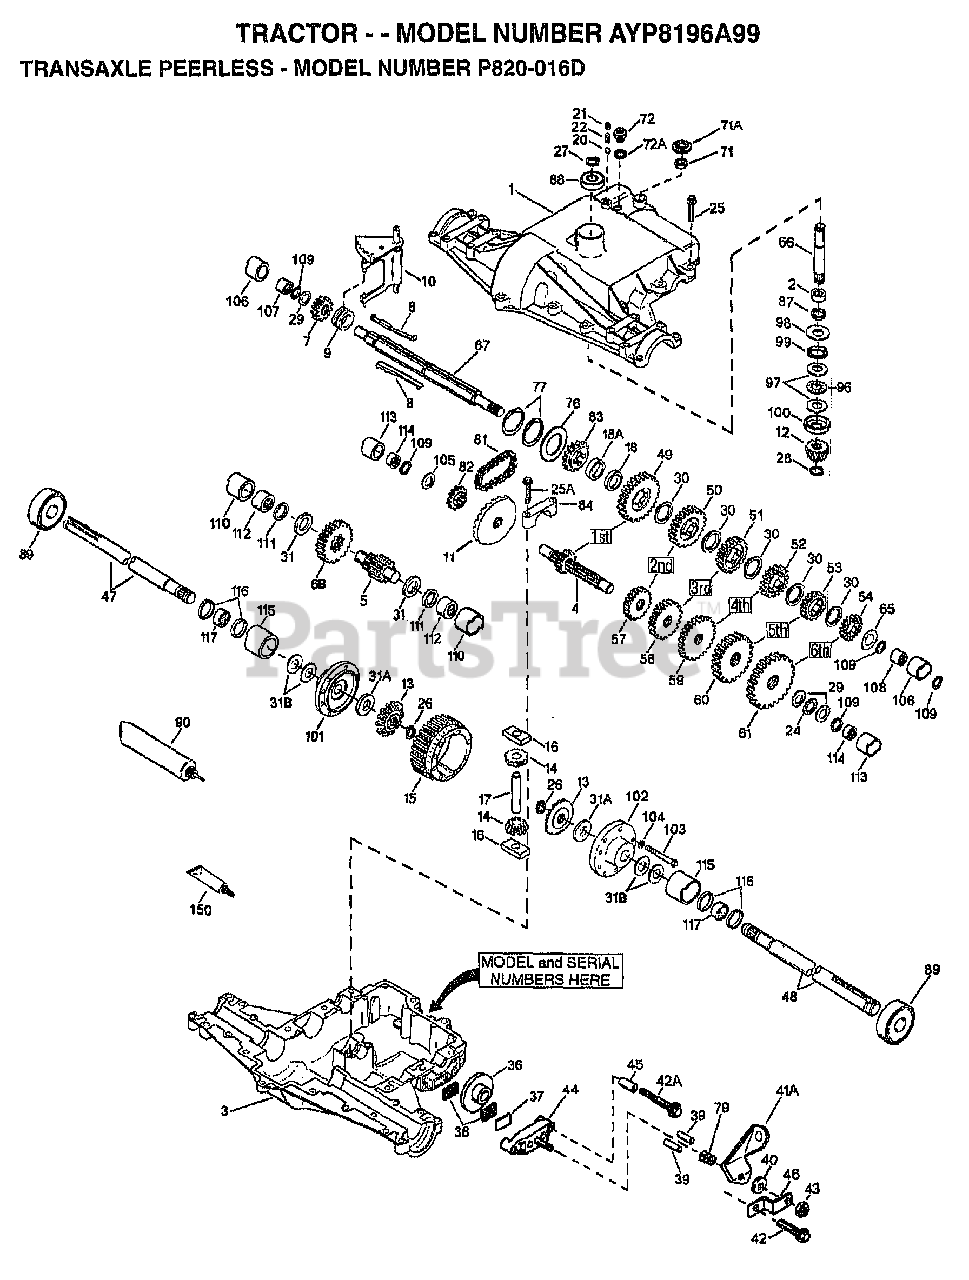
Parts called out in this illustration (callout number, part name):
1	COVER TRANSAXLE
2	BEARING NEEDLE
3	CASE TRANSAXLE
4	SHAFT COUNTER
5	SHAFT, OUTPUT, 9T
6B	GEAR, OUTPUT, 35T
7	GEAR, SPUR, 15T
9	COLLAR, SHIFTER
11	GEAR BEVEL, 33T
12	BEVEL PINION, 13T
14	PINION, 10T
15	GEAR, RING, 31T
16	BLOCK DRIVE
18	SPACER, .350/.340 THICK
18A	SPACER, .276/.268 THICK
20	BALL STEEL, 5/16" DIA.
21	SCREW, 3/8-16 X 3/8"
24	THRUST BEARING
25	SCREW, 5/16-18 X 1-1/4
28	RETAINING RING
29	WASHER THRUST
30	WASHER THRUST
31	WASHER THRUST
31B	WASHER THRUST
37	PLATE BRAKE PAD
41A	LEVER BRAKE
42A	SCREW, 1/4-20 X 2-1/4
43	LOCKNUT 5/16-24
44	HOLDER BRAKE PAD
46	BRKT BRAKE LEVER
47	AXLE, 12-5/16" LONG
48	AXLE, 16-3/16" LONG
49	GEAR, SPUR, 41T
50	GEAR, SPUR, 35T
51	GEAR, SPUR, 30T
52	GEAR, SPUR, 25T
53	GEAR, SPUR, 22T
54	GEAR, SPUR, 19T
57	GEAR, SPUR, 15T
58	GEAR, SPUR, 20T
59	GEAR, SPUR, 25T
60	GEAR, SPUR, 28T
61	GEAR, SPUR, 31T
65	WASHER, THRUST
66	SHAFT INPUT
67	SHIFTER & BRAKE SHAFT
71	SEAL SQUARE CUT
72	THREADED PLUG 9/16-18
76	WASHER, THRUST
77	INVERTED RETAINING RING
81	CHAIN, ROLLER
82	SPROCKET 9T
83	SPROCKET 18T (REV)
84	BEARING CAP
87	OIL SEAL 3/4
88	BEARING BALL
89	BEARING BALL
90	GREASE BENTONITE, 32 OZ.
96	BEARING THRUST
97	WASHER THRUST
100	WASHER CUPPED
101	CARRIER DIFF THREADED HOLES
102	CARRIER DIFF
103	SCREW, 1/4-20 X 2-1/4
104	WASHER LOCK 1/4
107	BEARING NEEDLE
108	BEARING NEEDLE
110	SLEEVE STEPPED
111	RING SQ CUT
112	BEARING NEEDLE CAPPED
113	SLEEVE STEPPED
114	BEARING NEEDLE CAPPED
115	SLEEVE STEPPED
116	RING SQ CUT
117	BEARING NEEDLE
150	LIQUID GASKET RTV SILICONE
